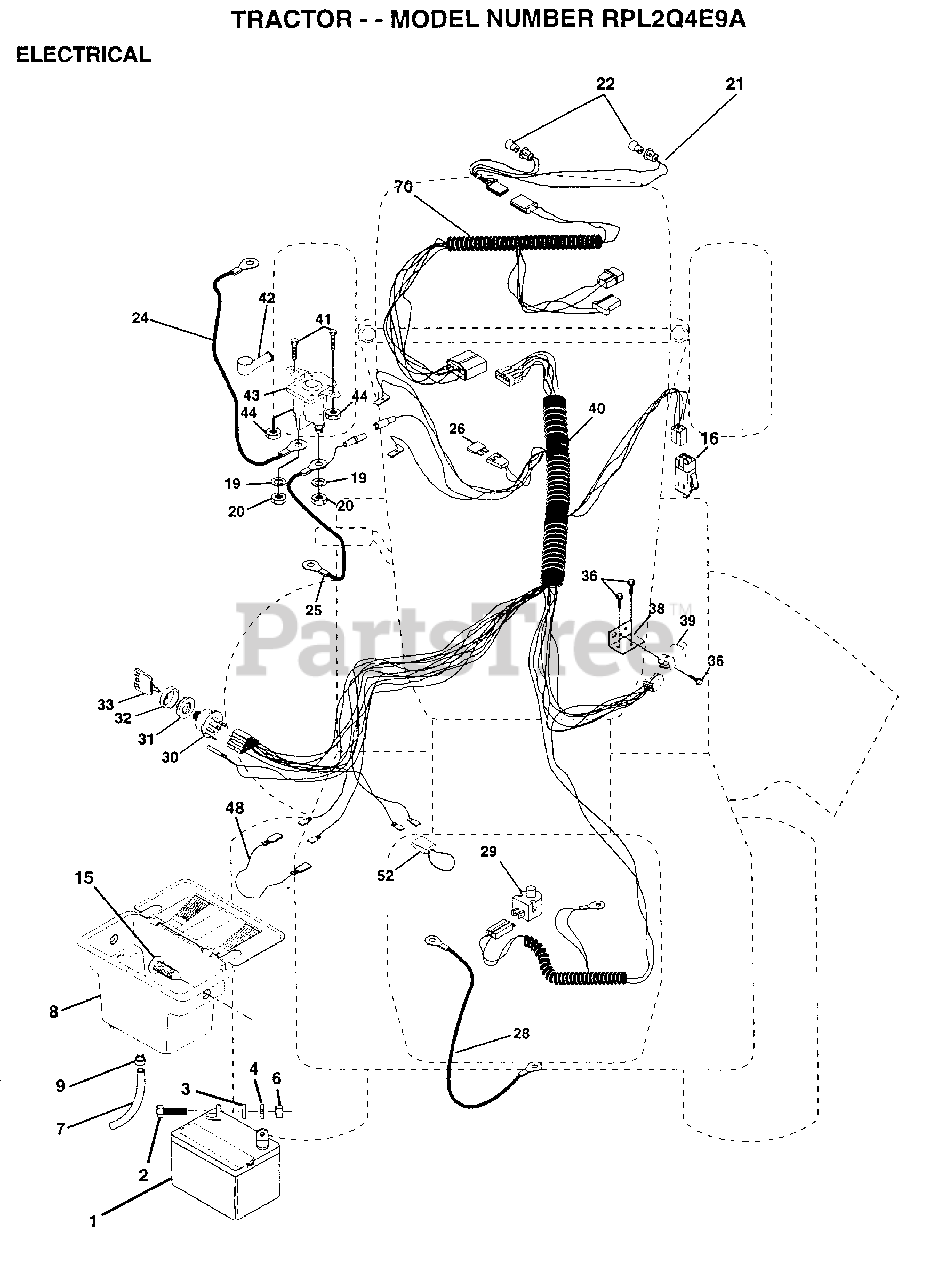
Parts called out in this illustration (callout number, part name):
2	BOLT LT
3	WASHER
4	LOCKWASHER
7	TUBE T
9	HOSE CLAMP T
15	FASTNER.SNAP-IN
16	SWITCH INTERLOCK
20	NUT
21	"HARNESS,LIGHT SOC"
22	HEADLAMP BULB
24	"CABLE T, BATTERY"
25	CABLE.BTRY.6GA.RD
26	FUSE HYT
28	CABLE T
29	SWITCH SEAT
30	SWITCH IGN 4POS
31	NUT IGNITION
32	COVER KEY SWITCH
33	KEY
36	SCREW
38	BRACKET SWITCH IN
39	SWITCH INTERLOCKT
40	HARNESS.IGNITION
41	BOLT HXHD FIN
44	NUT HXKEP 1/4X20
48	ADAPTER AMMETER
52	PROTECTION LOOP
70	HARNESS ENGINE
